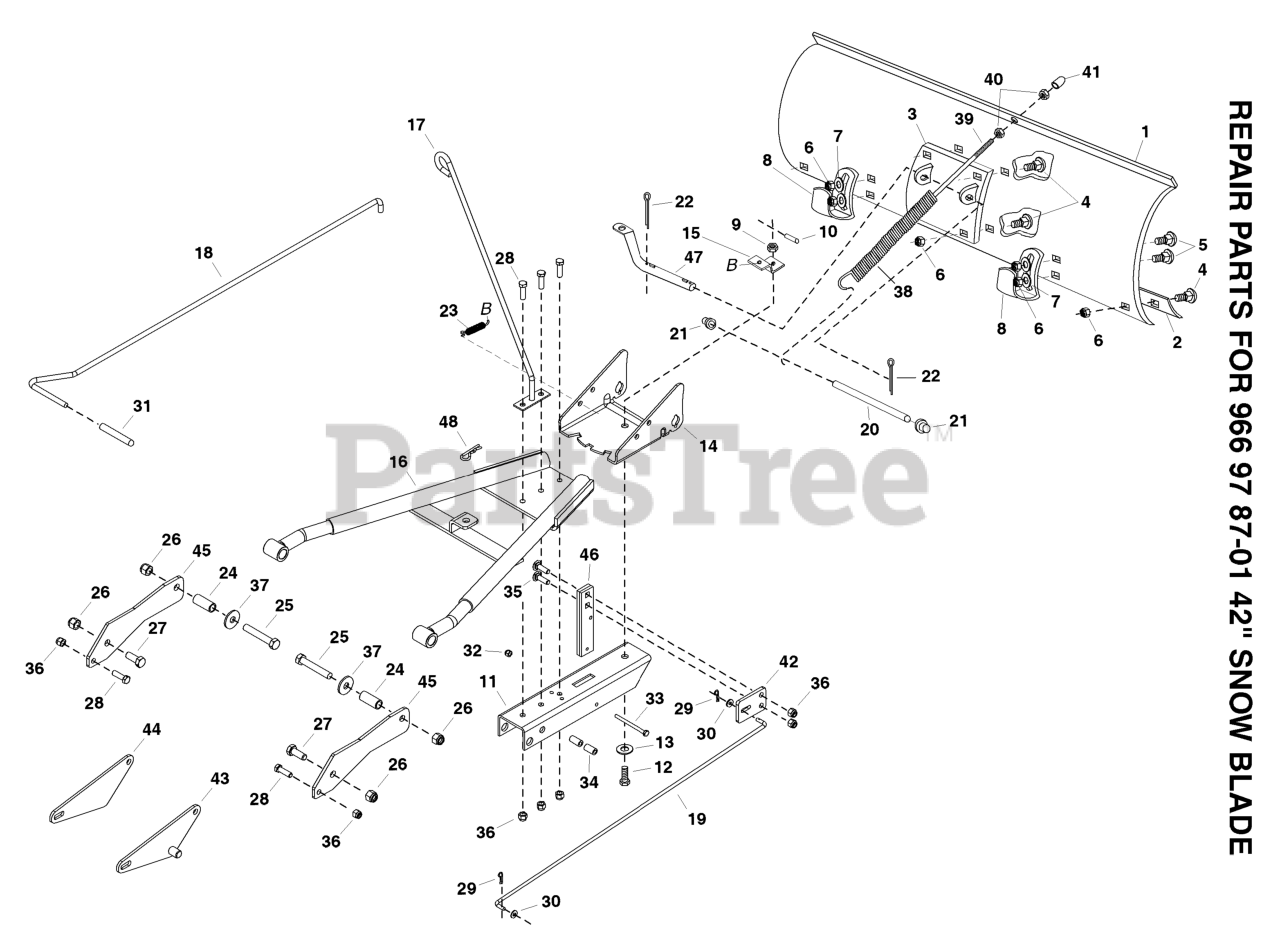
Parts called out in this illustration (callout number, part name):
2	MUFFLER.TWIN.CYL.LOW.TONE
9	KEEPER.BELT.ENGINE.4.2
11	CLUTCH.ELECTRIC.LT.48"*
12	PULLEY.ENGINE.TUFFTORQ
15	RP_TANK.ASM.4.GAL.CARB.2.PORT
18	RP CAP ASM
20	CONTROL THROTTLE/CHOKE
21	SCREW.#10 X 0.750.BOS
28	LINE.FUEL.64"REAR.EMIS
29	KIT.SPARK ARRESTOR 794945 B&S
37	HOSE CLAMP
42	LOCKWASHER
45	NUT
62	RP SHIELD HEAT MUFFLER
69	GASKET.MUFFLER
70	RP.EXHAUST.TUBE.LH.BS/TWIN
71	EXHAUST.TUBE.RH.BS/TWIN
79	SCREW.SOCKET.HEAD.5/16-18
84	SCREW.3/8-16
85	BOLT HEX 7/16-20X4-1/4"
87	BOLT 5/1618UNC X 3/4 W/ SEMS
90	SCREW 3/8-16X1
91	BUSHING.1.375OD
109	CANNISTER, CARBON
110	VALVE.ASM.ANTI-SLOSH
111	PURGE.LINE.36"REAR.CALIFORNIA
113	VALVE.SLANT.CARTRDG.90 DEG.TEX
116	RP KNOB SOFT TOUCH
117	VALVE FUEL RESERVE
